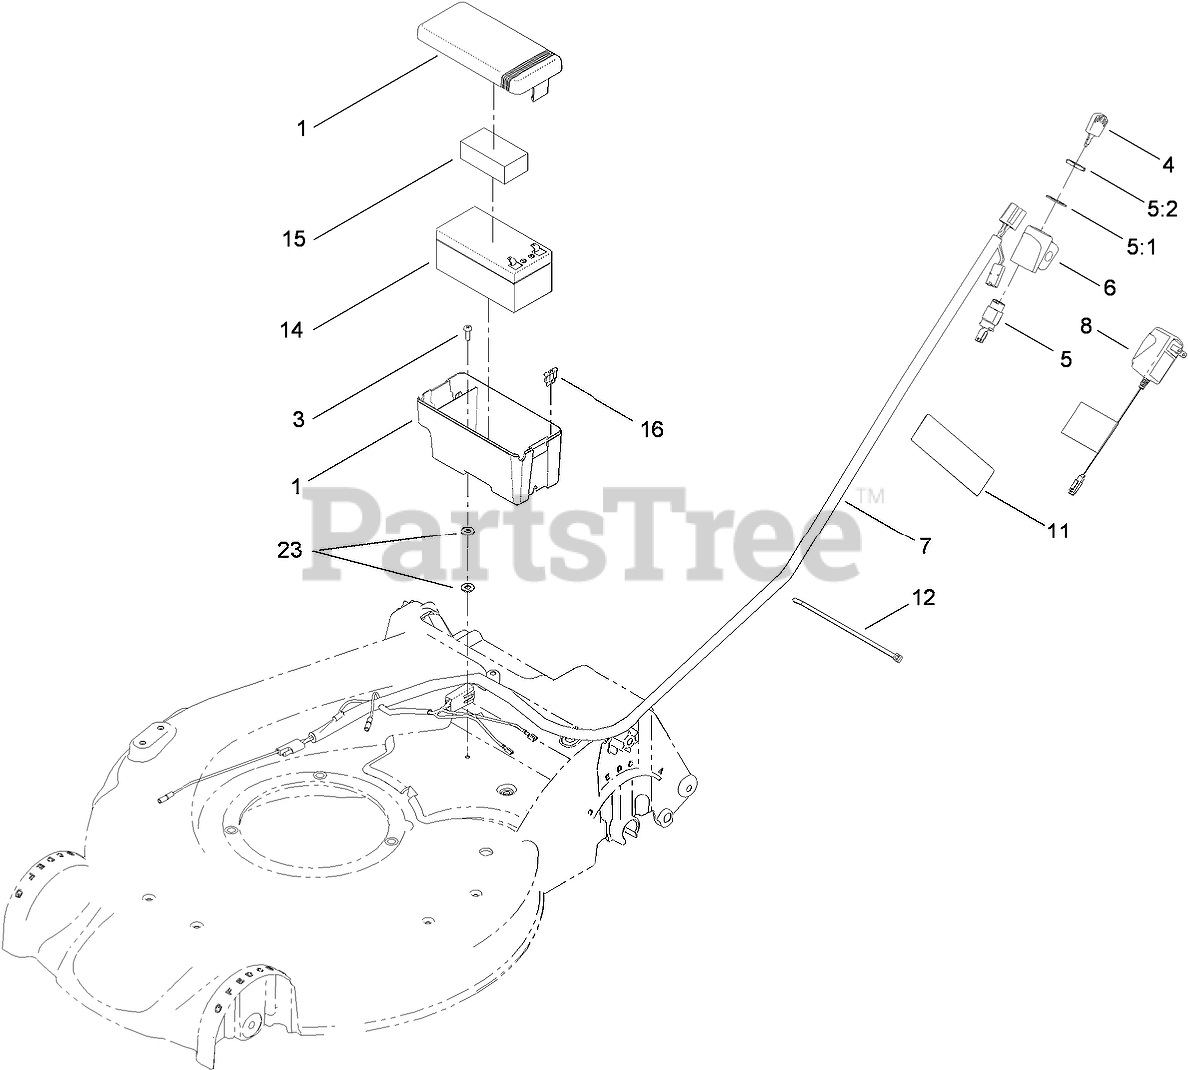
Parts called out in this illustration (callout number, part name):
1	BATTERY BOX ASM
5	STARTER SWITCH ASM
5:1	WASHER-TOOTH, INTERNAL
5:2	NUT-HH
6	MOUNT-SWITCH
7	HARNESS
8	CHARGER-EUROPEAN, 12V DC
11	DECAL-WARNING
12	TIE-CABLE
14	BATTERY-WET
15	FOAM-BATTERY, TOP
16	FUSE-40 AMP
23	WASHER-FLAT
